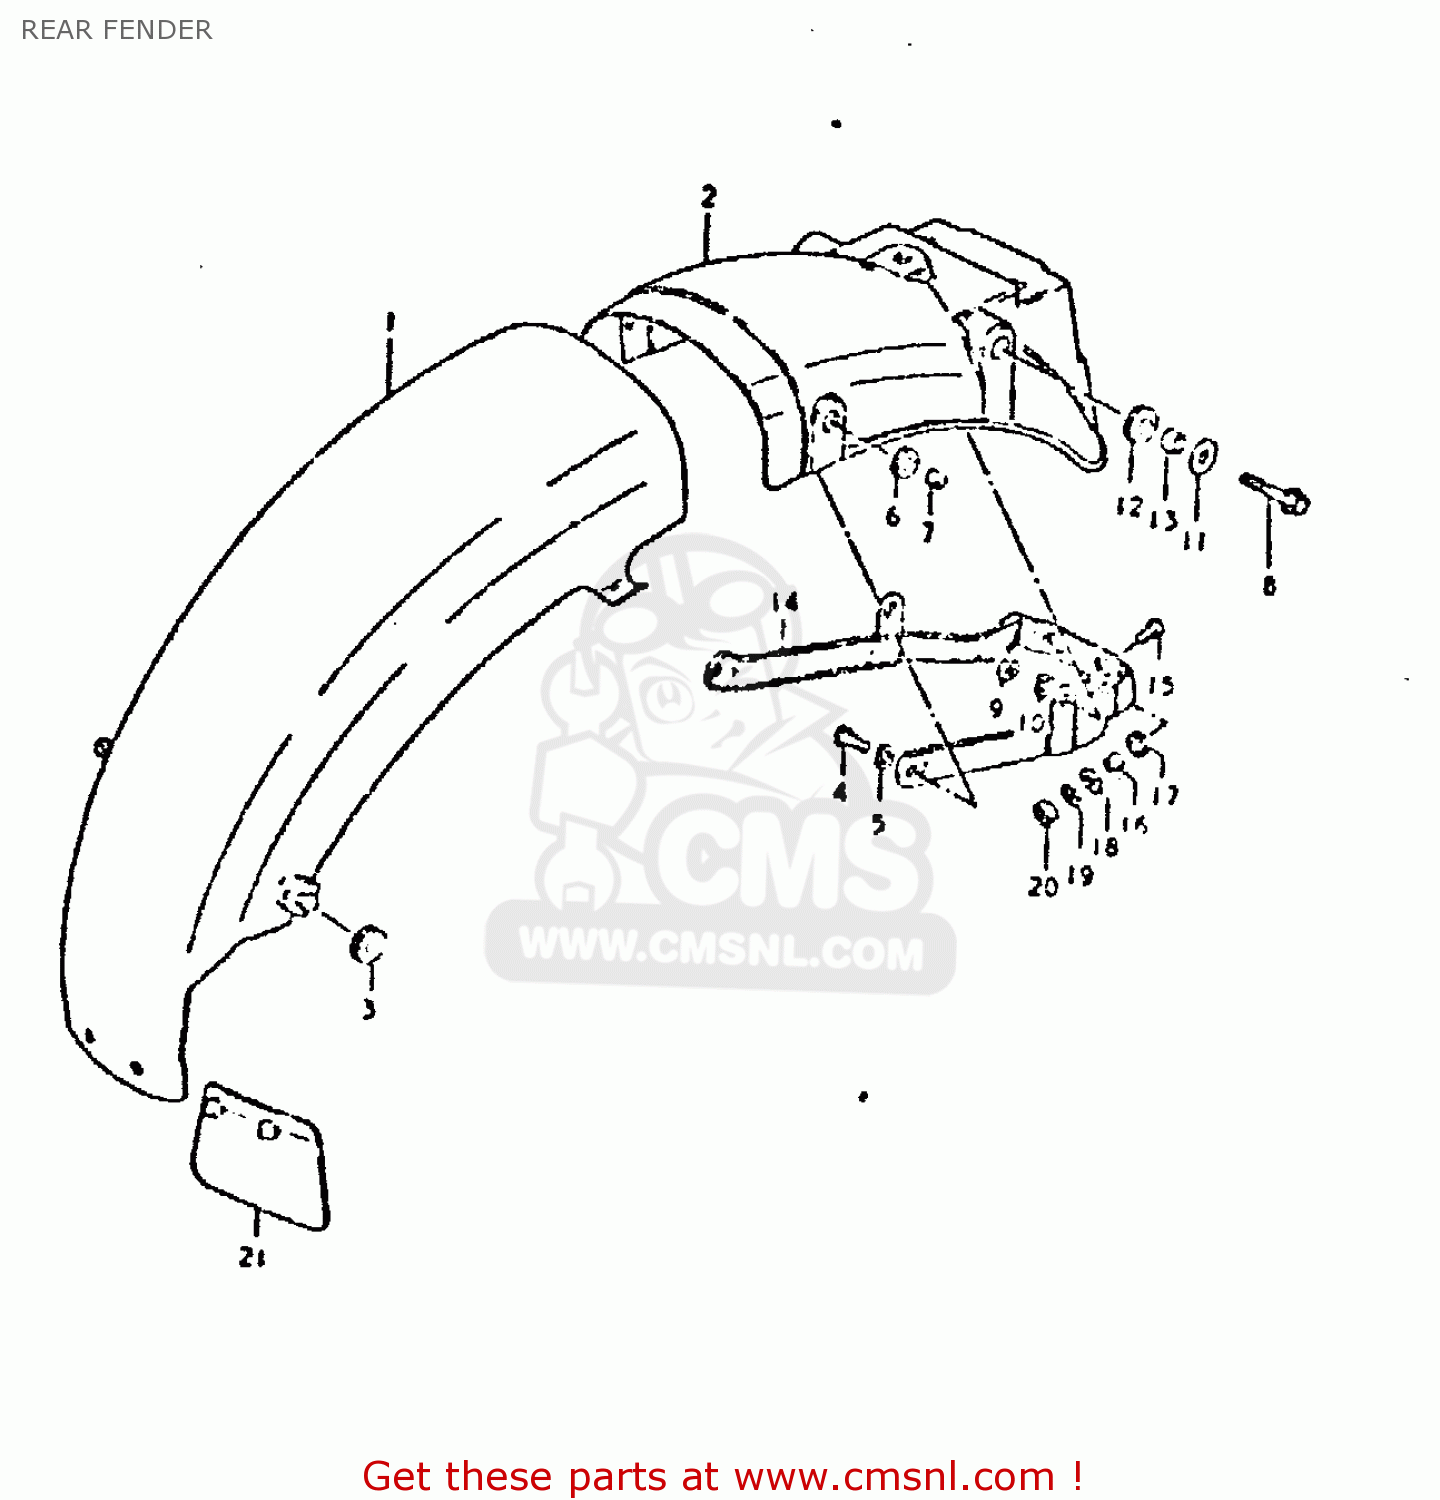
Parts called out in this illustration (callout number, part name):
1	FENDER,REAR
2	FENDER,REAR
3	CUSHION
4	BOLT
5	LOCK WASHER
6	CUSHION
7	SPACER(6.1X9X7.5)
8	BOLT
9	NUT
10	LOCK WASHER
11	WASHER(8.5X26X1.2)
12	CUSHION
13	SPACER (8.2X12X7.5)
14	REINFORCEMENT,REAR FENDER
15	SCREW
16	SPACER (6.1X9X9)
17	CUSHION
18	WASHER(6,5X22X1.6)
19	LOCK WASHER
20	NUT
21	GUIDE,RR FENDER MUD
